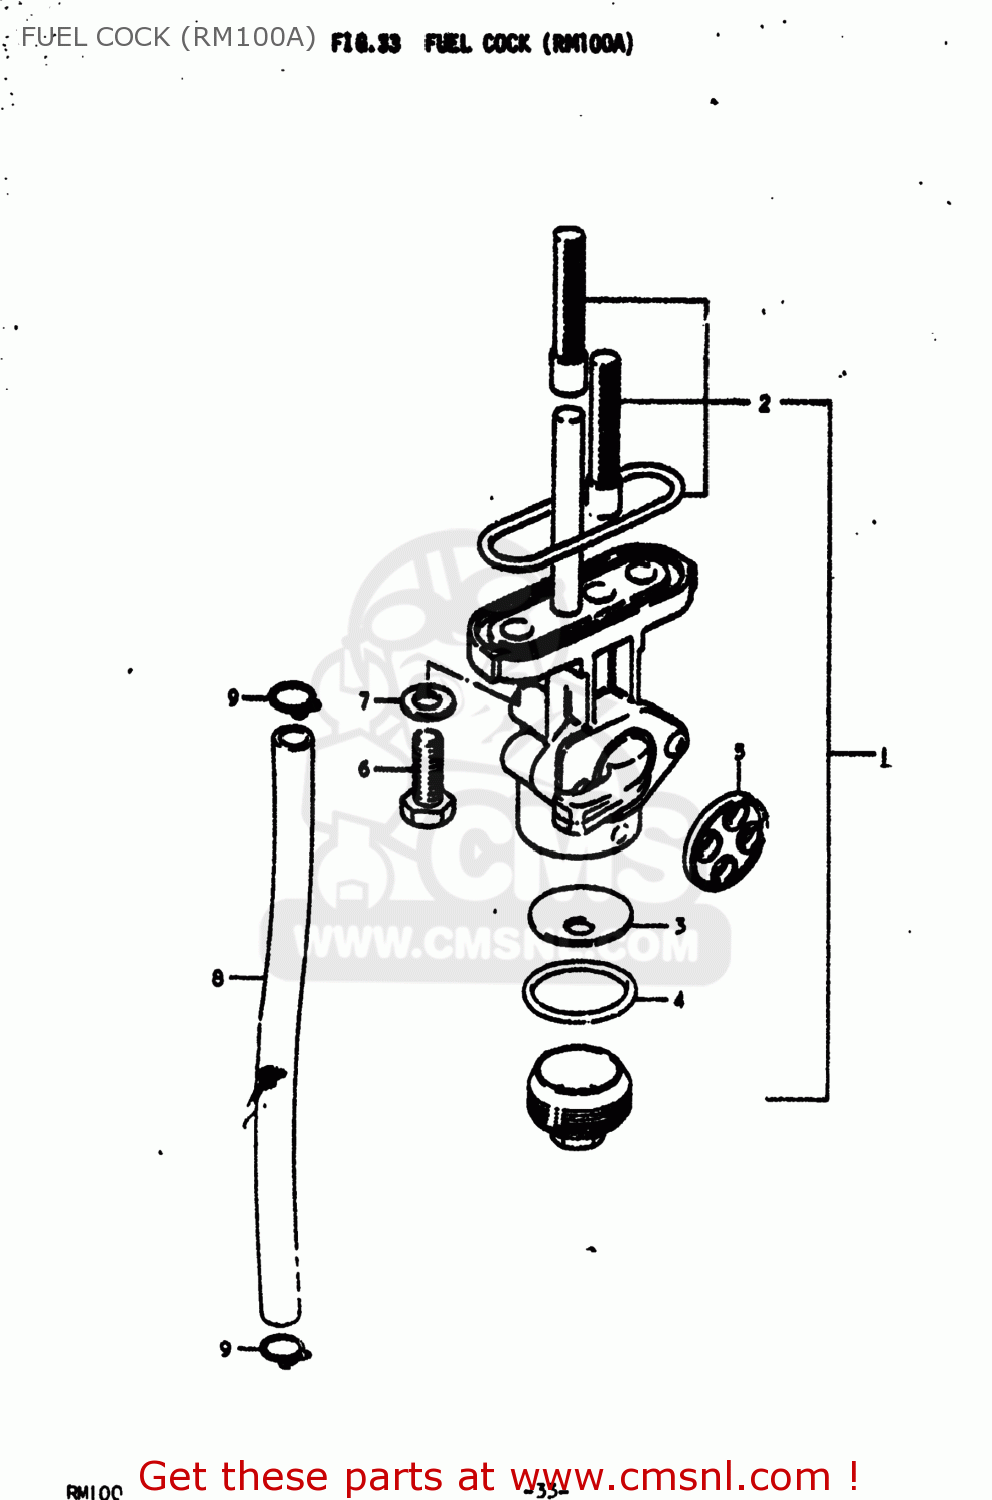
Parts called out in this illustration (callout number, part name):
1	COCK ASSEMBLY,FUEL
2	FILTER SET,FUEL COCK
3	NET,STRAINER
4	GASKET,FILTER (NAS)
5	GASKET,LEVER (NAS)
6	SCREW
7	GASKET
8	HOSE
9	CLIP
